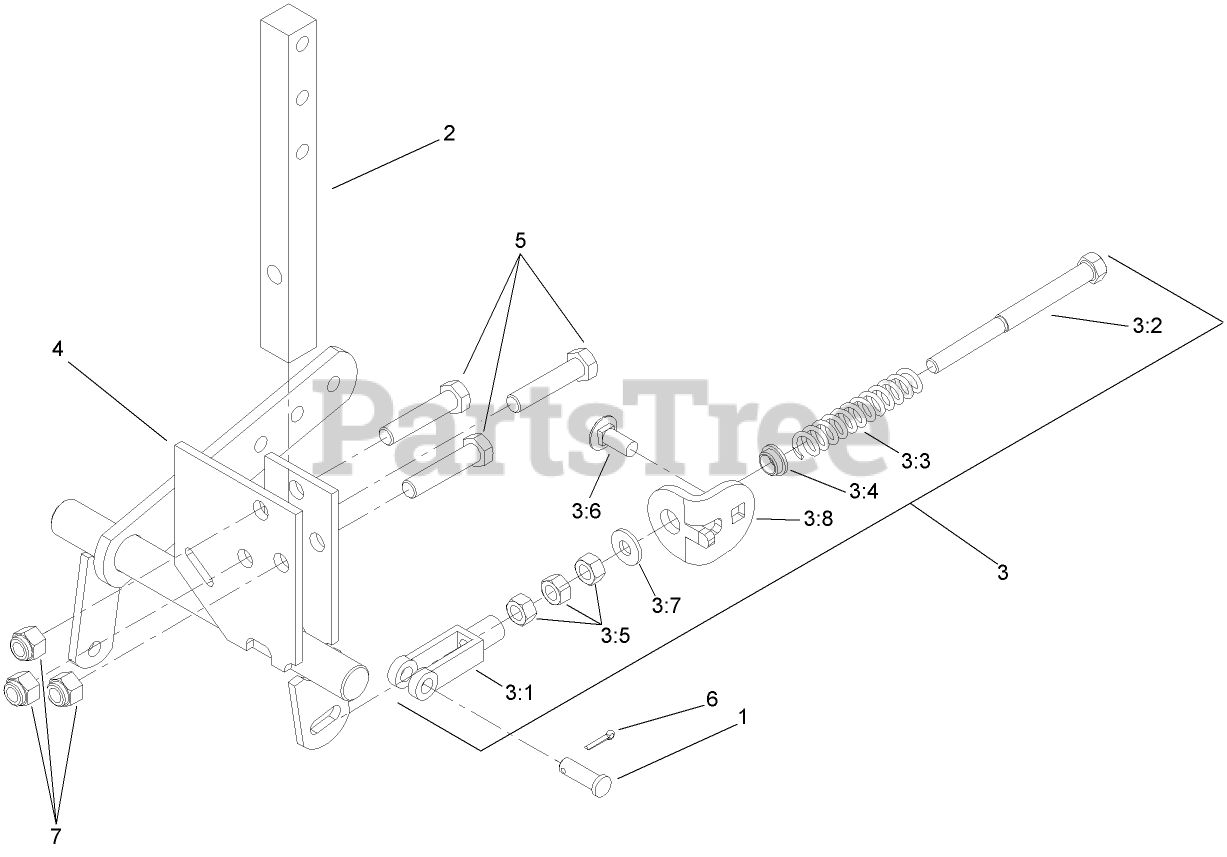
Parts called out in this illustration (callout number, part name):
1	PIN-CLEVIS
2	ARM-SHAFT, CONTROL
3	NEUTRAL RETURN ASM
3:1	YOKE-ADJUSTABLE
3:2	BOLT-RETURN, NEUTRAL
3:3	SPRING-RETURN, NEUTRAL
3:4	BUSHING-NYLON, FLANGED
3:5	NUT-HEX
3:6	SCREW-CARR
3:7	WASHER-FLAT
3:8	TAB-ADJUSTMENT
4	CONTROL-MOTION, LH
5	SCREW-HH
6	PIN-COTTER
7	NUT-LOCK, NI
